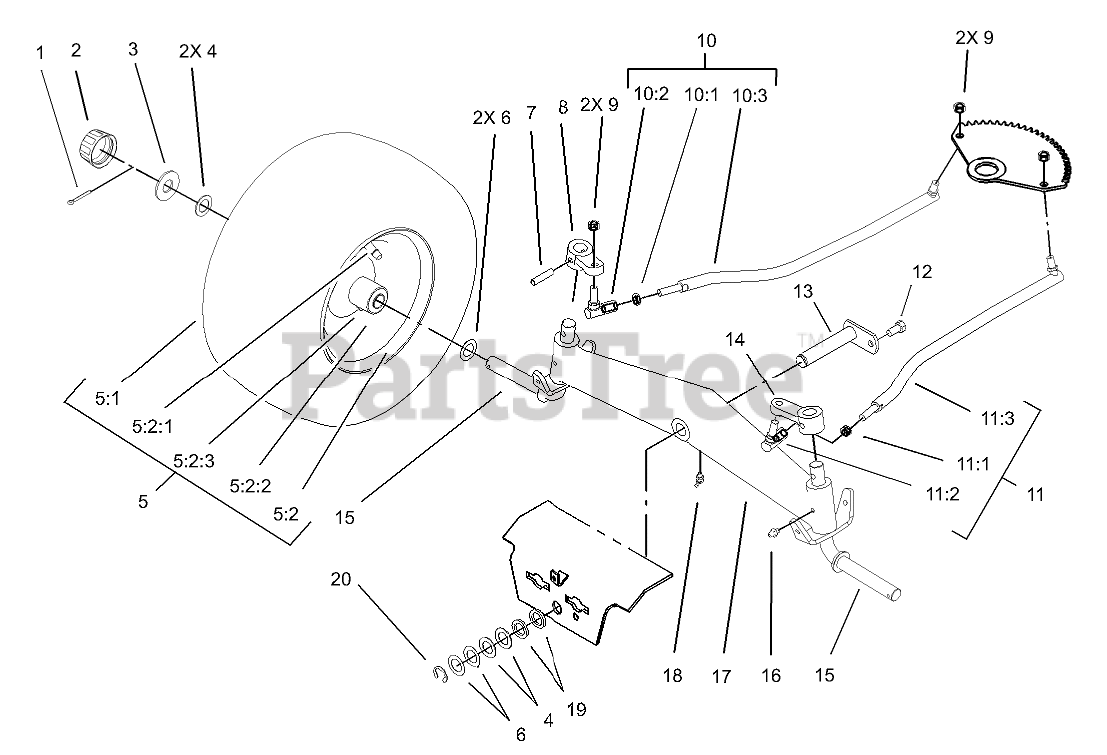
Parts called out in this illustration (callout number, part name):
1	PIN-COTTER
2	CAP-HUB
3	WASHER-PLAIN
4	WASHER
5	FRONT WHEEL & TIRE ASM
5:2	Wheel ASM
5:2:1	VALVE
5:2:2	BEARING-WHEEL
5:2:3	ZERK-GREASE
6	WASHER-SHIM
8	Arm-Front Spindle
10	LINKAGE-STEERING, RH
10:1	NUT-JAM
10:2	BALL-JOINT
10:3	Ball Link ASM
11	LINKAGE-STEERING, LH
11:1	NUT-JAM
11:2	BALL-JOINT
11:3	Ball Link ASM
12	SCREW-HWH, TAPTITE
13	PIN-AXLE
14	Arm-Front Spindle
15	SPINDLE
16	FITTING-GREASE
17	AXLE-FRONT
18	FITTING-LUBE, 45 DEG
19	Washer
20	E-RING
